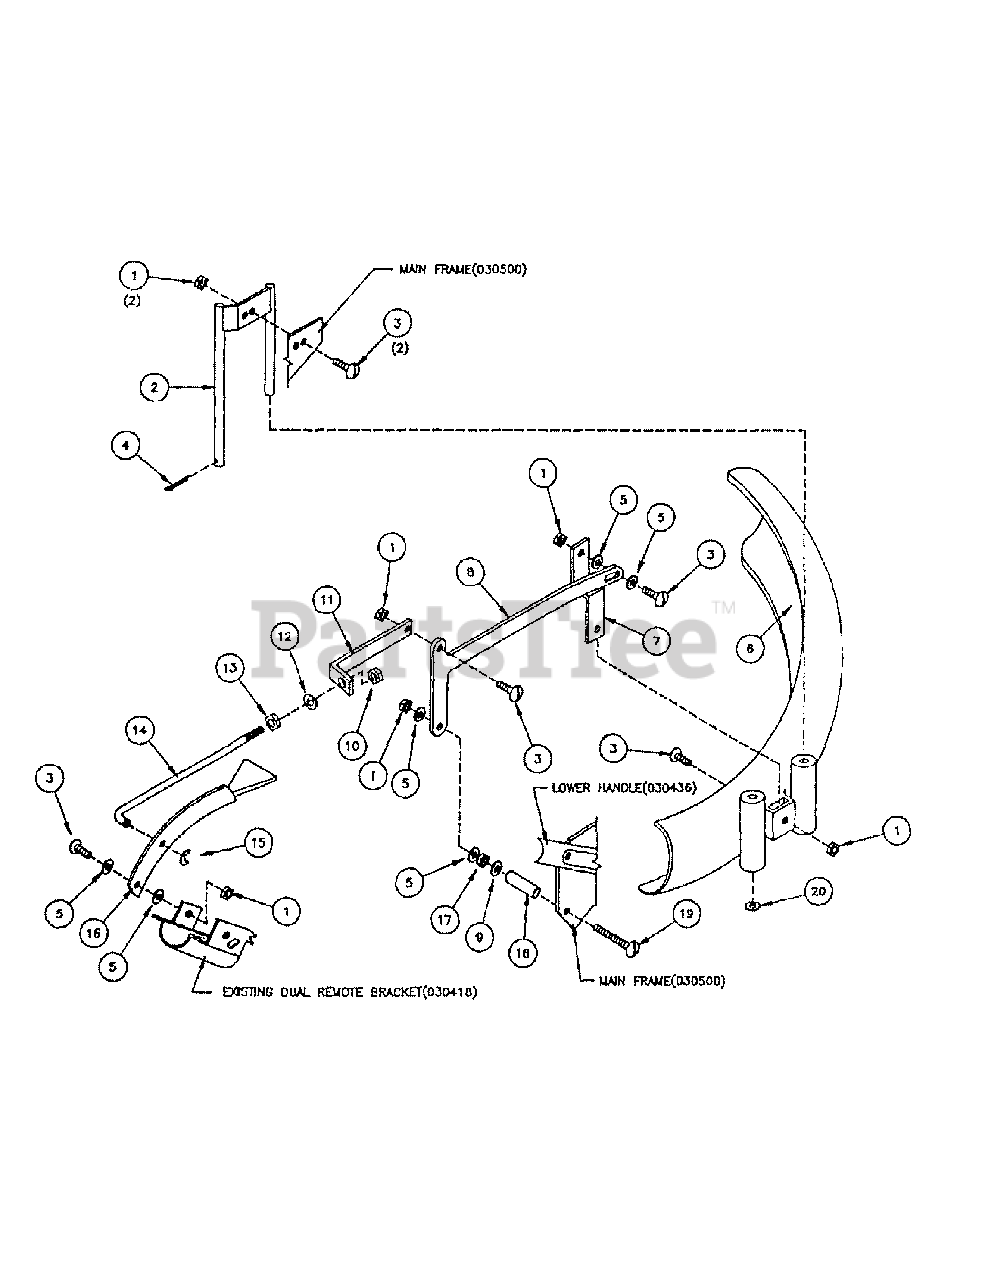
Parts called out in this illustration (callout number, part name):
1	Hex Nut, 1/4-20 Nylock SS
2	Deflector Mount Assembly
3	Pan Hd. Mach. Scr. 1/4-20x7/8
4	Cotter Pin, 1/8 x 1" SS
5	Flatwasher, 1/4 Nylon
6	Deflector Tube
7	Offset Bracket
8	Deflector Lift Arm
9	Flatwasher, 1/4 SS
10	Hex Nut, 5/16-18 Nylock SS
11	Deflector Adjusting Bracket
12	Lockwasher, 5/16 SS
13	Hex Nut, 5/16-18, SS
14	Deflector Control Rod
15	C-Clip Retainer
16	Operating Lever and Rubber Handle
17	Hex Nut, 1/4-20 SS
18	Deflector Arm Mounting Spacer
19	Machine Screw, 1/4-20 x 2 SS
20	Flatwasher, 3/8 SS
